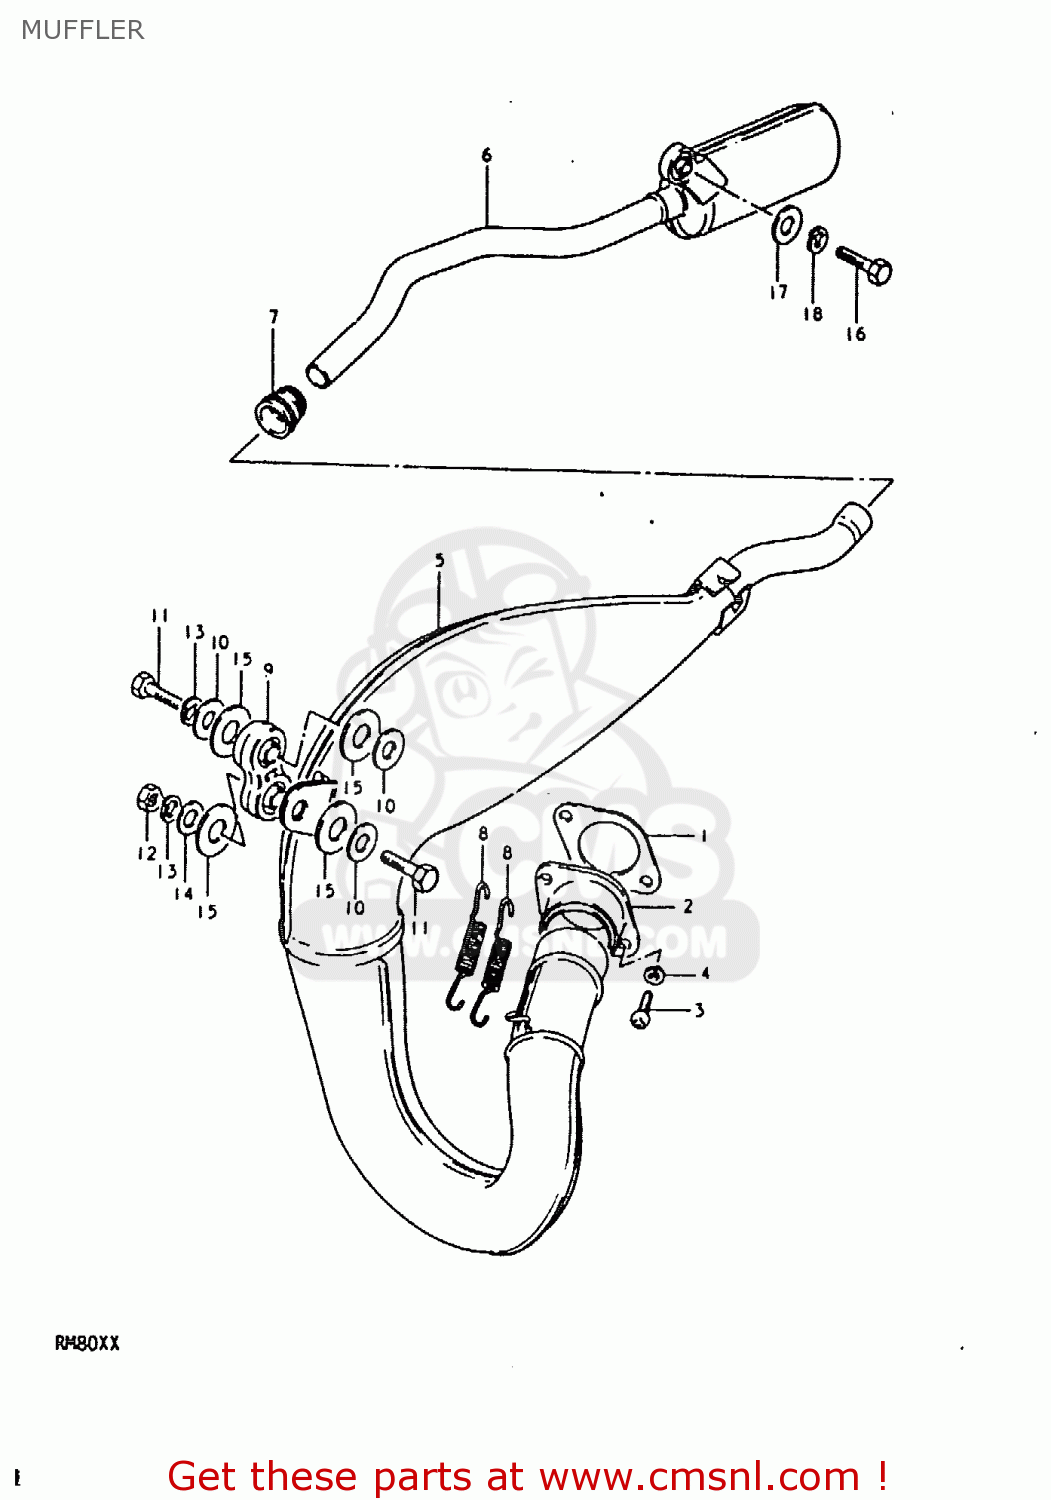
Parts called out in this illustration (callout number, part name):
1	GASKET,EXHAUST PIPE (MCA)
2	PIPE,CENTER EXHAUST
3	SCREW
4	LOCK WASHER
5	BODY,MUFFLER
6	BODY,MUFFLER
7	CONNECTOR,MUFFLER
8	SPRING
9	DAMPER,MUFFLER
10	WASHER
11	BOLT
12	NUT
13	LOCK WASHER
14	WASHER
15	WASHER(13X28X1.6)
16	BOLT
17	WASHER
18	LOCK WASHER
